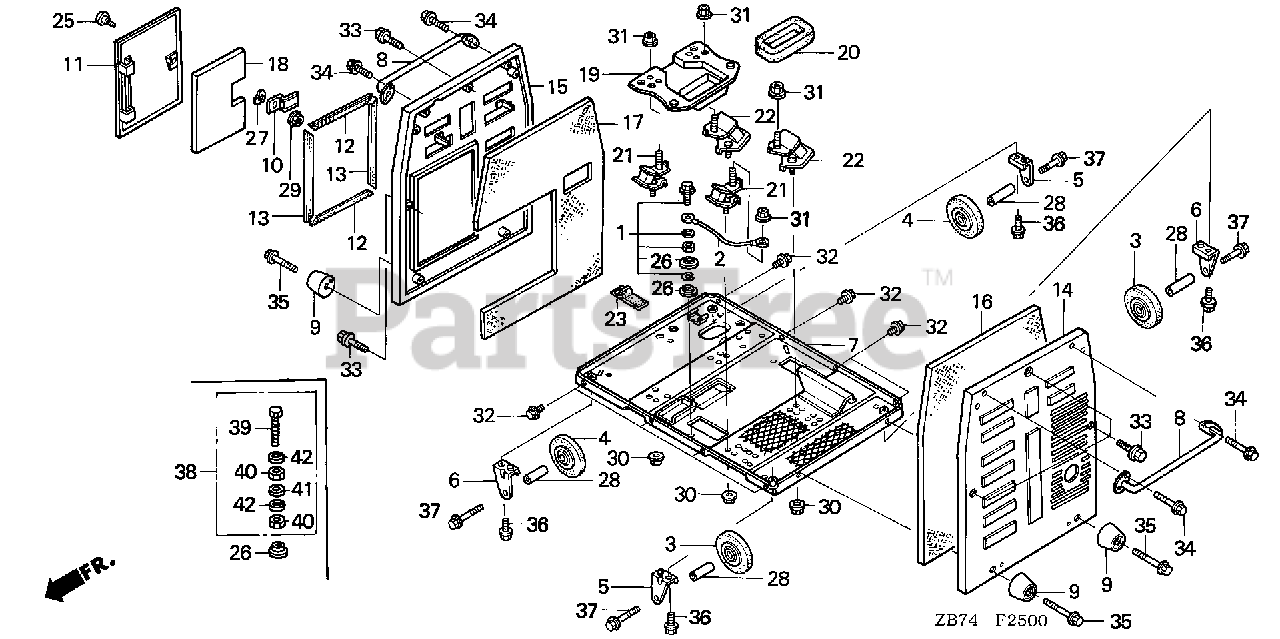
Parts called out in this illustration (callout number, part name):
1	TERMINAL ASSY., GROUND
2	CABLE, GROUND
3	WHEEL (100X32)
4	WHEEL (100X32)
5	BRACKET, R. WHEEL
6	BRACKET, L. WHEEL
7	FRAME (LOWER) *NH105* (MAT BLACK)
8	HANDLE *NH105* (MAT BLACK)
9	RUBBER (LOWER) Use from Frame SN 1008046.
10	PLATE, MAINTNENANCE LID LOCK
11	LID, MAINTENANCE *NH105* (MAT BLACK)
12	SEAL C, MAINTENANCE LID
13	SEAL D, MAINTENANCE LID
14	PANEL, R. SIDE *NH105* (MAT BLACK)
15	PANEL, L. SIDE *NH105* (MAT BLACK)
16	INSULATOR, R. SIDE PANEL
17	INSULATOR, L. SIDE PANEL
18	INSULATOR, RR. MAINTENANCE LID
19	GUIDE, AIR (LOWER)
20	SEAL, AIR GUIDE (LOWER)
21	RUBBER (LOWER)
22	RUBBER (LOWER)
25	BOLT, MAINTENANCE LID LOCK
26	NUT, SPECIAL (6MM)
27	WASHER, WAVE (12MM)
28	COLLAR, WHEEL SHAFT
29	NUT, FLANGE (6MM)
30	NUT, FLANGE (8MM)
31	NUT, FLANGE (10MM)
32	BOLT, FLANGE (6X12)
33	BOLT, FLANGE (6X35)
34	BOLT, FLANGE (6X35)
35	BOLT, FLANGE (6X35)
36	BOLT, FLANGE (8X16) Use from Engine SN 1000016.
37	BOLT, FLANGE (8X55)
38	TERMINAL SET, GROUND
39	BOLT, HEX. (6X28)
40	NUT, HEX. (6MM)
41	WASHER, PLAIN (6MM)
42	WASHER, SPRING (6MM)
